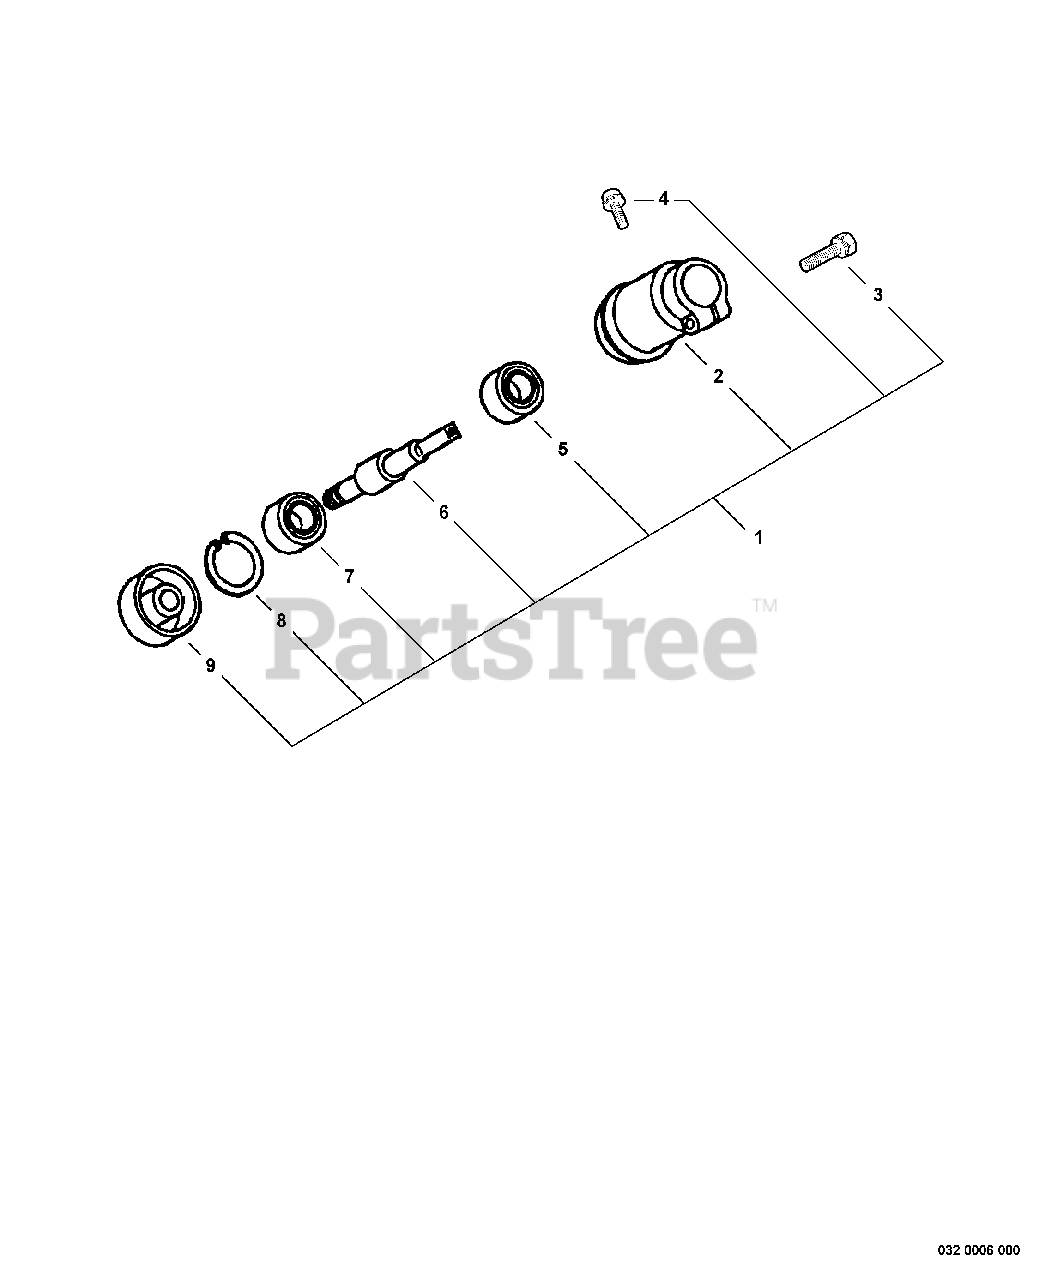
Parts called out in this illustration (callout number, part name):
1	GEAR CASE ASSY
2	CASE, GEAR
3	BOLT - 5X25
4	SCREW - 4X10
5	BEARING, BALL - 6200
6	GEAR - SHAFT
7	BEARING, BALL - 6200
8	RING, RETAINING - 30
9	ADAPTOR, BLADE - UPPER
